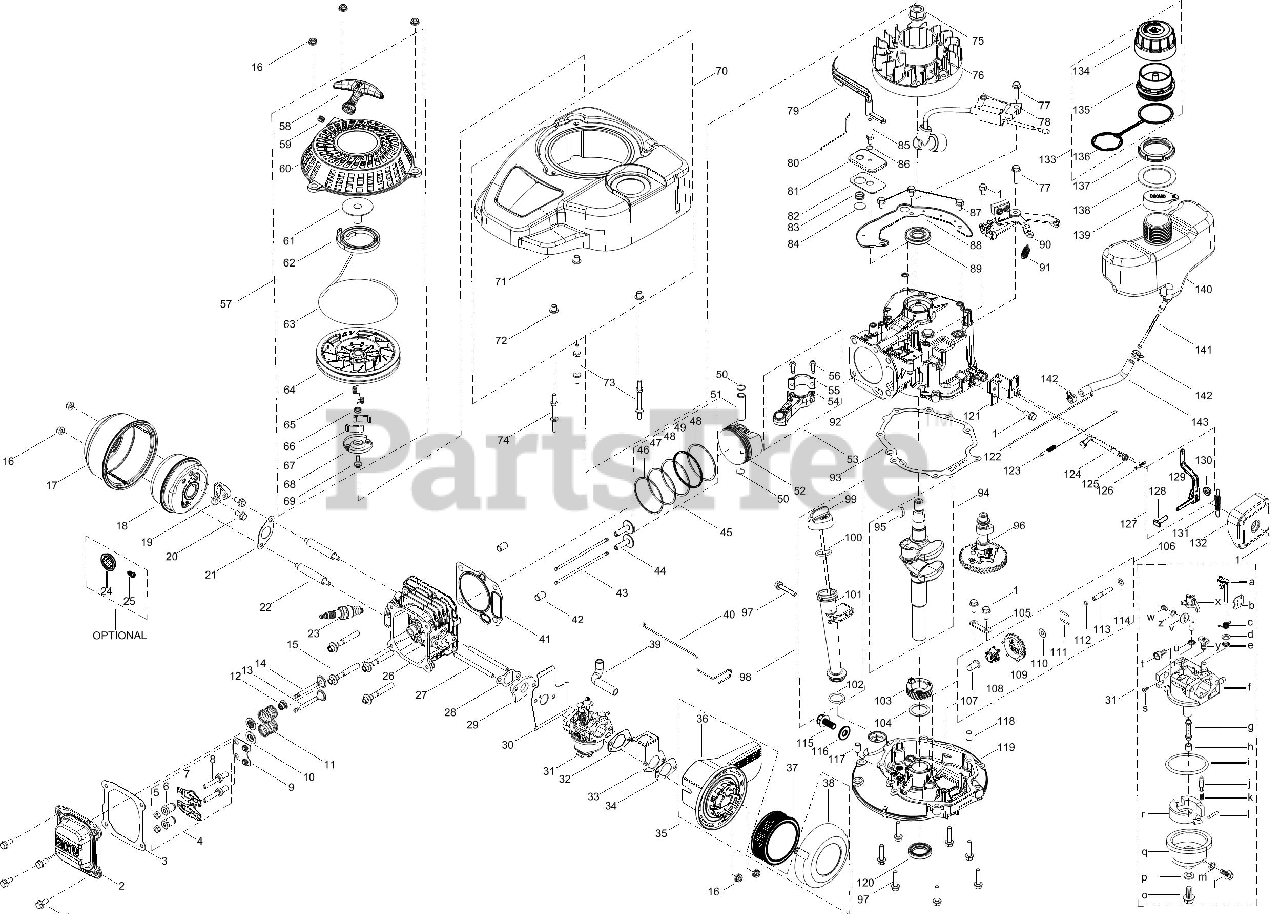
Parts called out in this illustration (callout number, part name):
1	Bolt M6X14
2	Valve Cover
3	Valve Cover Gasket
4	Rocker Arm Assembly
6	Fulcrum Nut
7	Rocker Arm
8	Rocker Arm Stud
9	Push Rod Guide
10	Valve Spring Retainer
11	Valve Spring
12	Intake Valve Seal
13	Exhaust Valve
14	Intake Valve
15	Bolt M8X54
17	Muffler Shield
18	Muffler Assembly
19	Autochoke Temp-Comp Control
20	Bolt M6X12
21	Muffler Gasket
22	Muffler Stud M6X76
23	Spark Plug/F5RTC
24	Spark Arrestor
25	Spark Arrestor Screw
26	Cylinder Head
26	Cylinder Head (Svc Kit)
27	Carb Stud M6X87
28	Carburetor Insulator Gasket
29	Carburetor Insulator
30	Carburetor Gasket
31	Carburetor Assembly
32	Choke Temp Control Bracket Gasket
33	Choke Temp Control Bracket
34	Air Filter Base Gasket
35	Air Filter Assembly
36	Air Filter Base
37	Air Filter Element, Paper
38	Air Filter Cover
39	Breather Hose
40	Temp Control Linkage
41	Cylinder Head Gasket
42	Cylinder Head Dowel Pin 10X16
43	Push Rod
45	Piston Ring Set
46	Upper Piston Compression Ring
47	Lower Piston Compression Ring
48	Piston Oil Ring Segment
49	Piston Oil Ring Expander
50	Piston Pin Snap Ring
51	Piston Pin
52	Piston
53	Connecting Rod Assembly
54	Connecting Rod
55	Connecting Rod Cap
56	Connecting Rod Bolt
57	Starter Recoil Assembly
58	Starter Handle
59	Starter Housing Rope Eyelet
60	Starter Housing
61	Starter Shaft
62	Recoil Spring
63	Starter Rope
64	Starter Pulley
65	Starter Pawl Return Spring
66	Pressure Plate Spring
67	Starter Pawl
68	Pressure Plate
69	Pressure Plate Bolt
70	Engine Shroud Assembly
71	Engine Shroud
72	Engine Shroud Spacer
73	Shroud Stud M6X75
74	Shroud Stud M6X73
75	Flywheel Nut M14
76	Flywheel
77	Bolt M6X25
78	Ignition Coil Assembly
80	Choke Linkage
81	Breather Cover Plate
82	Breather Gasket
83	Breather Valve Spring
84	Breather Valve
85	Air Vane Pivot Stud
86	Air Vane Pivot Washer
87	Bolt M6X10
88	Shroud Cover Plate
89	Upper Crankshaft Seal
90	Brake Assembly
91	Brake Spring
93	Crankcase Cover Gasket
94	Crankshaft Assembly
95	Flywheel Key
96	Camshaft Assembly
97	Bolt M6X28
98	Dipstick Assembly
99	Dipstick
100	Dipstick / Oil Fill Tube O-Ring
101	Dipstick Tube / Oil Fill
102	Dipstick / Oil Fill Tube O-Ring
103	Timing Gear
104	Crankshaft Thrust Washer
105	Governor Gear Mounting Plate
106	Governor Gear/Shaft Assembly
107	Governor Slide Cap
108	Governor Fly Weight
109	Governor Gear
110	Governor Slide Cap Washer
111	Governor Fly Weight Pin
112	Governor Shaft Stop Ring
113	Governor Gear Shaft
114	Governor Gear Washer
115	Oil Drain Plug
116	Oil Drain Plug Washer
117	Crankcase Cover Dowel Pin 9X14
118	Crankcase Cover Dowel Pin 7X14
119	Crankcase Cover
120	Lower Crankshaft Seal
121	Component Bracket
122	Throttle Linkage
123	Throttle Linkage Spring
124	Governor Arm Shaft
125	Governor Seal
126	Governor Arm Shaft Cotter Pin
127	Governor Arm Assembly
128	Governor Arm Bolt
129	Governor Arm
131	Governor Spring
132	Governor Shield
133	Fuel Cap Assembly
134	Fuel Cap Cover
135	Fuel Cap Cover
136	Fuel Cap Tether
137	Fuel Tank Nut
138	Fuel Tank Upper Grommet
139	Fuel Tank Dust Cap
140	Fuel Tank
141	Fuel Filter
142	Fuel Hose Clamp
143	Fuel Hose
